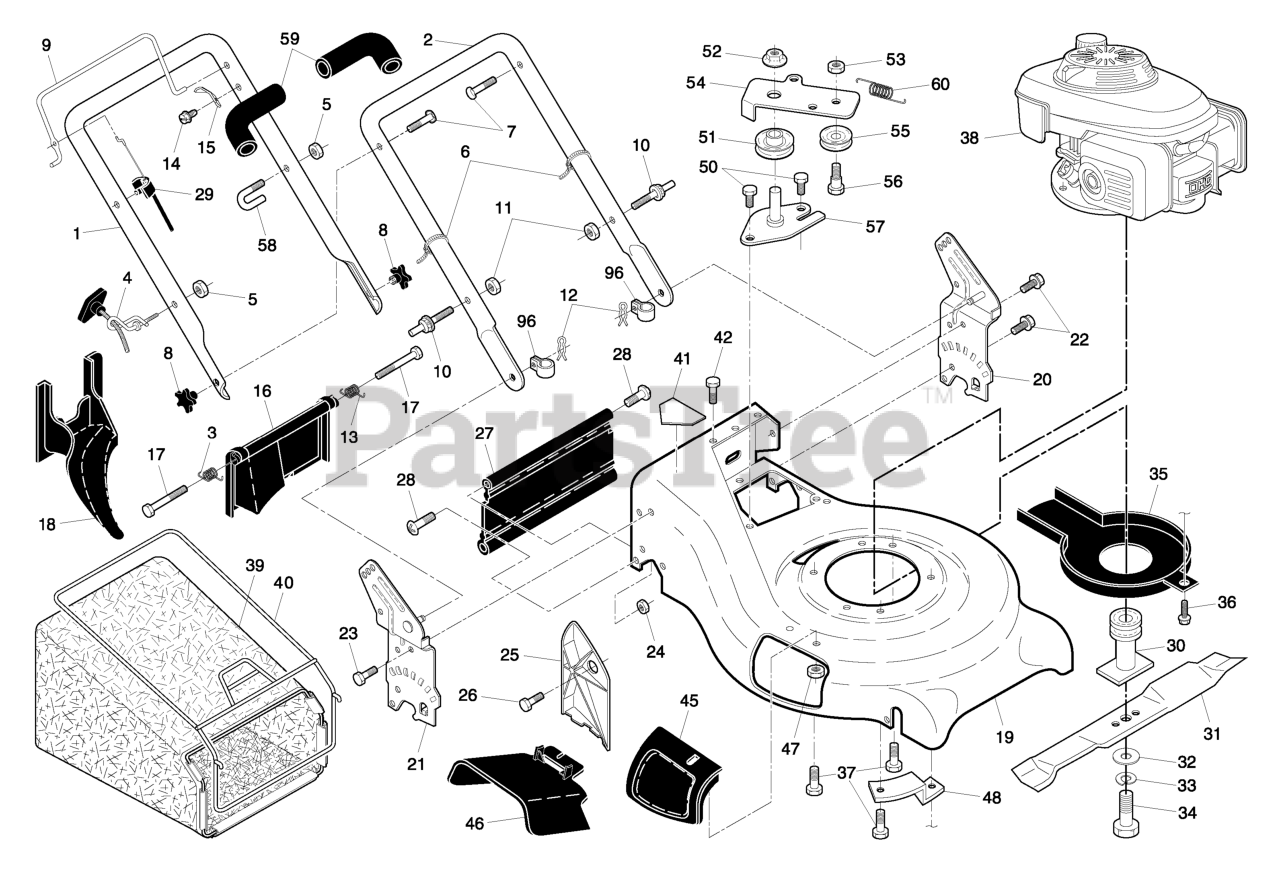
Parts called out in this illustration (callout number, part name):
1	HANDLE.ASM.UP.OFF/EZ.CR.W/GRIP
2	HANDLE.LOWER.21.GREY
3	SPRING.RH.REAR.DOOR.21.RWGD
4	RB GUIDE.ROPE.STD.BLK.ZIN WSL
5	NUT
6	TIE GUIDE
7	BOLT, HANDLE 5/16-18X1.75
8	KNOB.HANDLE.STAR.HUSQ.GRAY
9	BAIL.DSTRT.FL.AW.CREAS.ORANGE
11	NUT.LOCK.5/16-18
12	HAIRPIN COTTER
13	SPRING.LH.REAR.DOOR.21.RWGD
15	BRACKET UPSTOP
16	REAR DOOR ASSEMBLY
18	PLUG.MULCHER.RGD.21.
19	HOUSING.21.RWD.ORANGE.WALK.
20	BRKT.ASM.HNDL.21.RWGD.LT
21	BRKT.ASM.HNDL
22	SELF-TAPPING SCREW 5/16-18X3/4
23	BOLT, HEX HEAD 5/16-18
24	NUT.71038.31-18.HEX.NYLOCK
25	CLIPPING DEFLECTOR
27	SKIRT, REAR
28	HINGE SCREW
29	SNAP-ON.ZONE.CABLE.ASS
30	BLADE ADAPTOR / PULLEY
31	BLADE.21.PUSH/RWGD/FWGD
32	WASHER,HARDEN
33	LOCKWASHER
34	SCREW, HEX HD 3/8-24 X 1-3/8
35	DEBRIS SHEILD
36	SCREW.HEX.WSH
37	BOLT 3/8-16X1-1/8
38	Engine, Honda
39	GRASSBAG
40	FRAME, GRASSBAG
41	DANGER DECAL
45	LEVER, SELECTOR, HEIGHT, FRONT
46	DEFLECTOR, DISCHARGE
48	BRACKET
51	PULLEY.IDLER.V-BELT
52	NUT
53	LOCKNUT
54	ARM.IDLER
55	IDLER PULLEY
56	SHOULDER BOLT
57	BRACKET.IDLER.ASM.EZ
59	GRIP.HANDLE.FOAM.WIDE.(1 SIDE)
60	SPRING, RETURN
96	CLIP.CABLE.BLK
